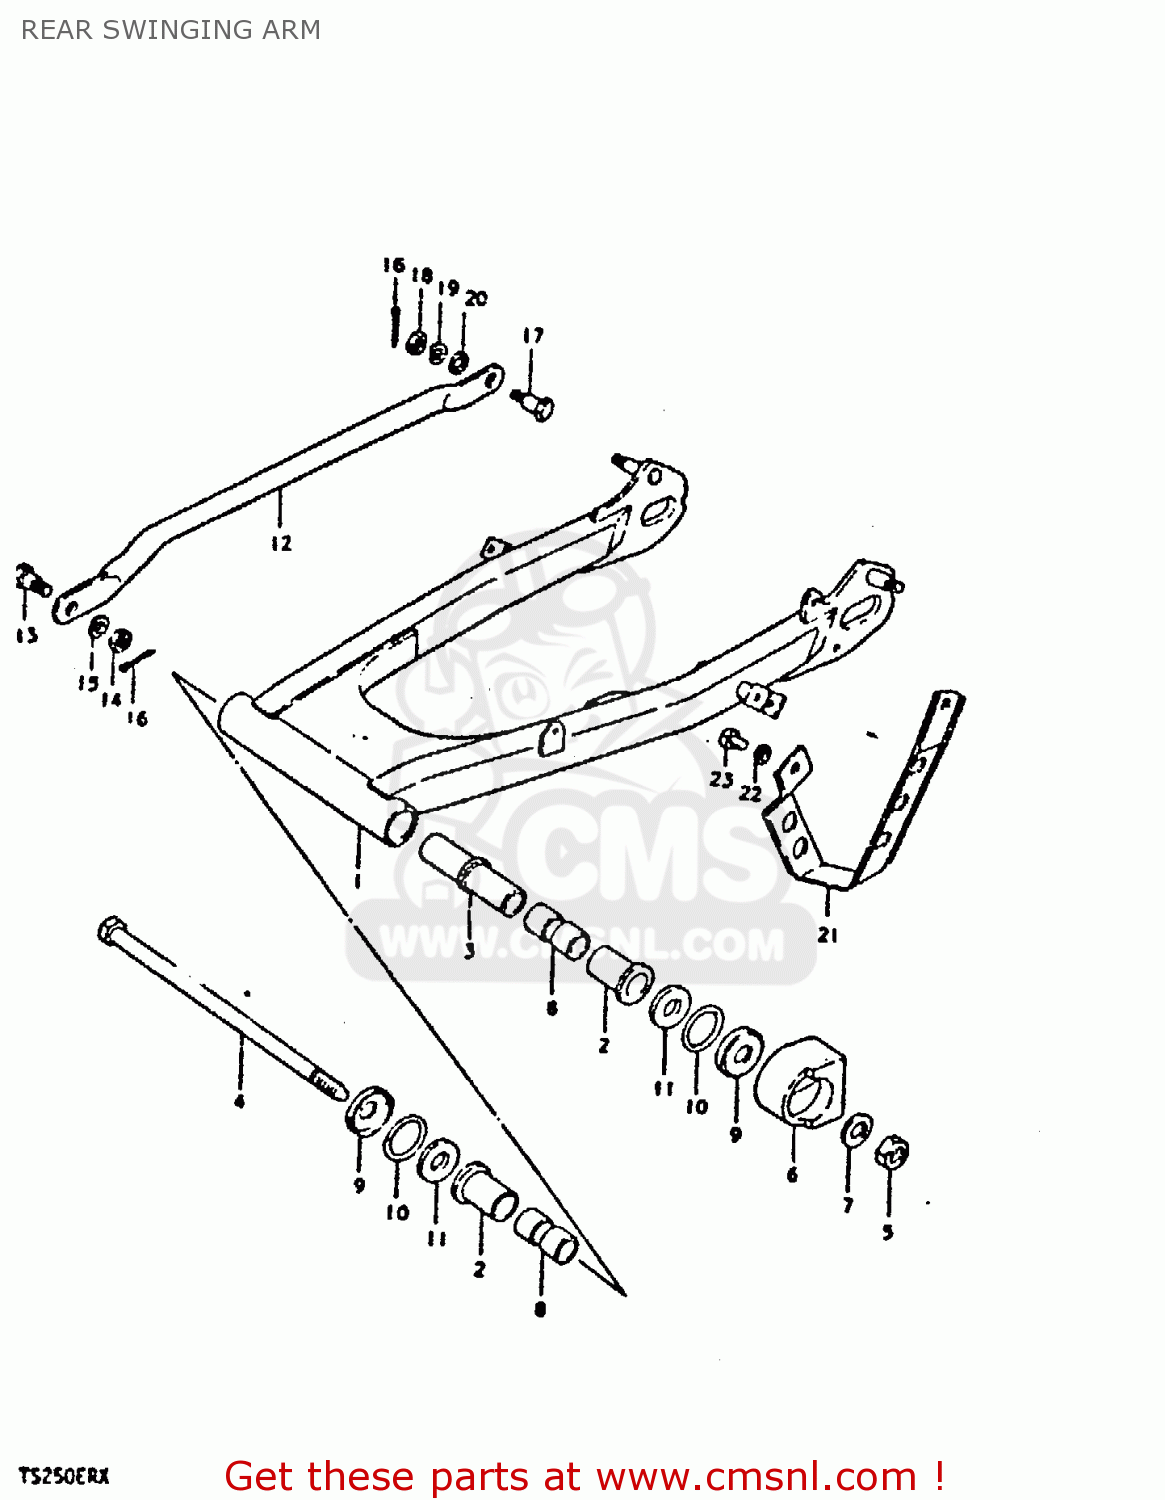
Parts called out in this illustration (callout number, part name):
1	SWING ARM ASSEMBLY,REAR
2	BUSH
3	SPACER,SWING ARM,CENTER
4	SHAFT,REAR SWING ARM
5	NUT 14MM
6	BUFFER,CHAIN TOUCH DEFLECTOR
7	WASHER
8	SPACER
9	COVER
10	O RING(D:3,ID:29.5)
11	WASHER(14.5X29X2.3)
12	TORQUE LINK,REAR
13	BOLT(8X22.5)
14	NUT
15	LOCK WASHER
16	PIN
17	BOLT(10X32.5)
18	NUT
19	LOCK WASHER
20	WASHER
21	GUIDE,CHAIN
22	LOCK WASHER
23	BOLT 8X12
